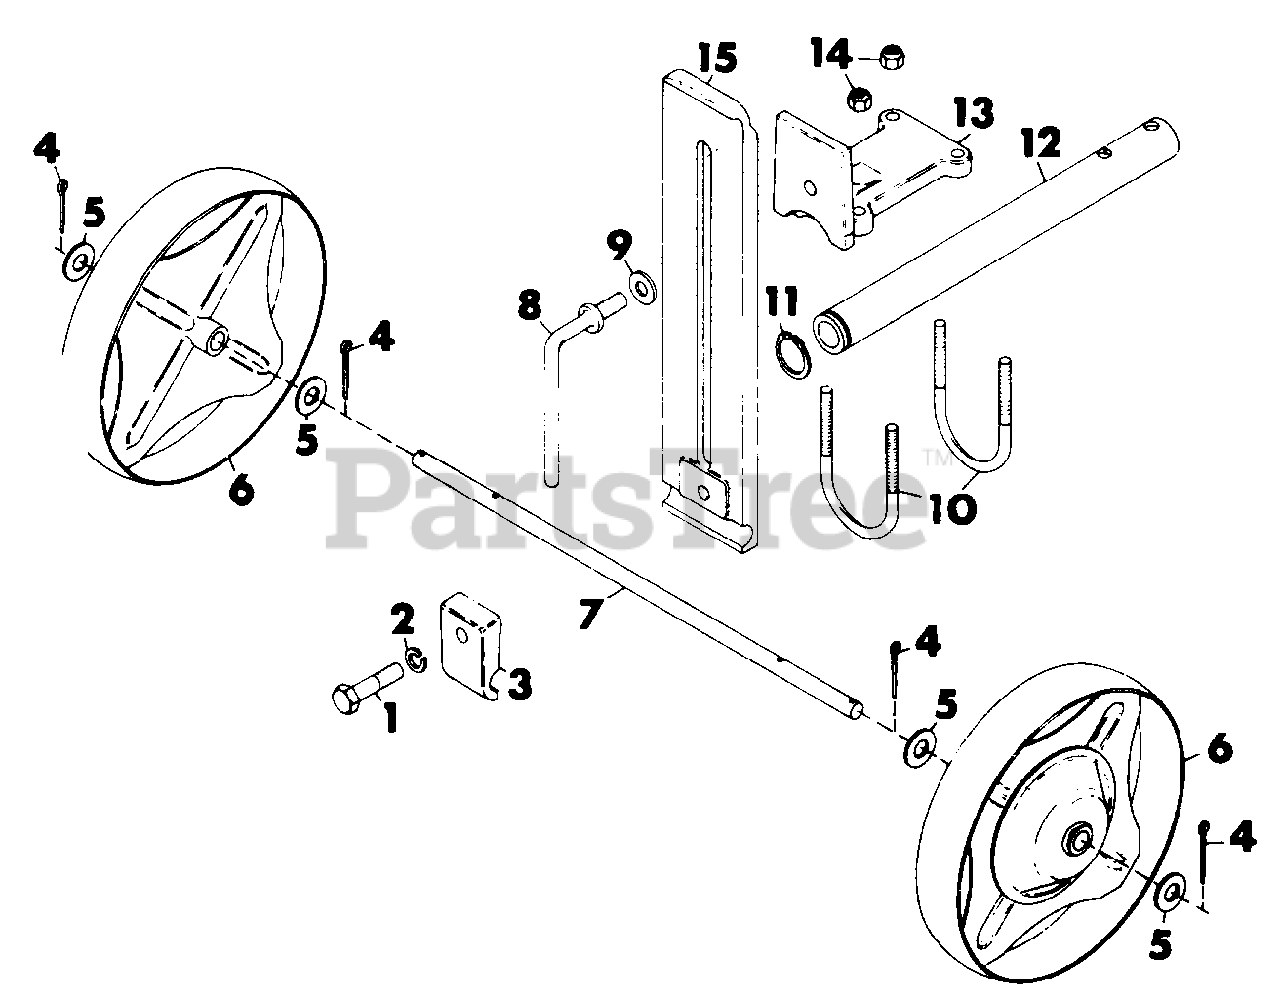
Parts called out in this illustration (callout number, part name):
1	BOLT, HEX 1/2-13X1.50
2	WASHER, LOCK 1/2 REG.
3	CLAMP, AXLE
4	PIN, COTTER .187X1.62
5	WASHER, FLAT .812X1.496X.134
6	WHEEL, DEPTH
7	AXLE, DEPTH WHEEL
8	SCREW, WHEEL BRACKET CLAMP
9	WASHER, FLAT .563X1.375X.109
10	BOLT-U, 3/8-16
11	RING, SNAP TRUARC 5160-193
12	SUPPORT, TUBE
13	SWIVEL, WHEEL BRACKET
14	NUT, LOCK 3/8-16
15	BRACKET, WHEEL
